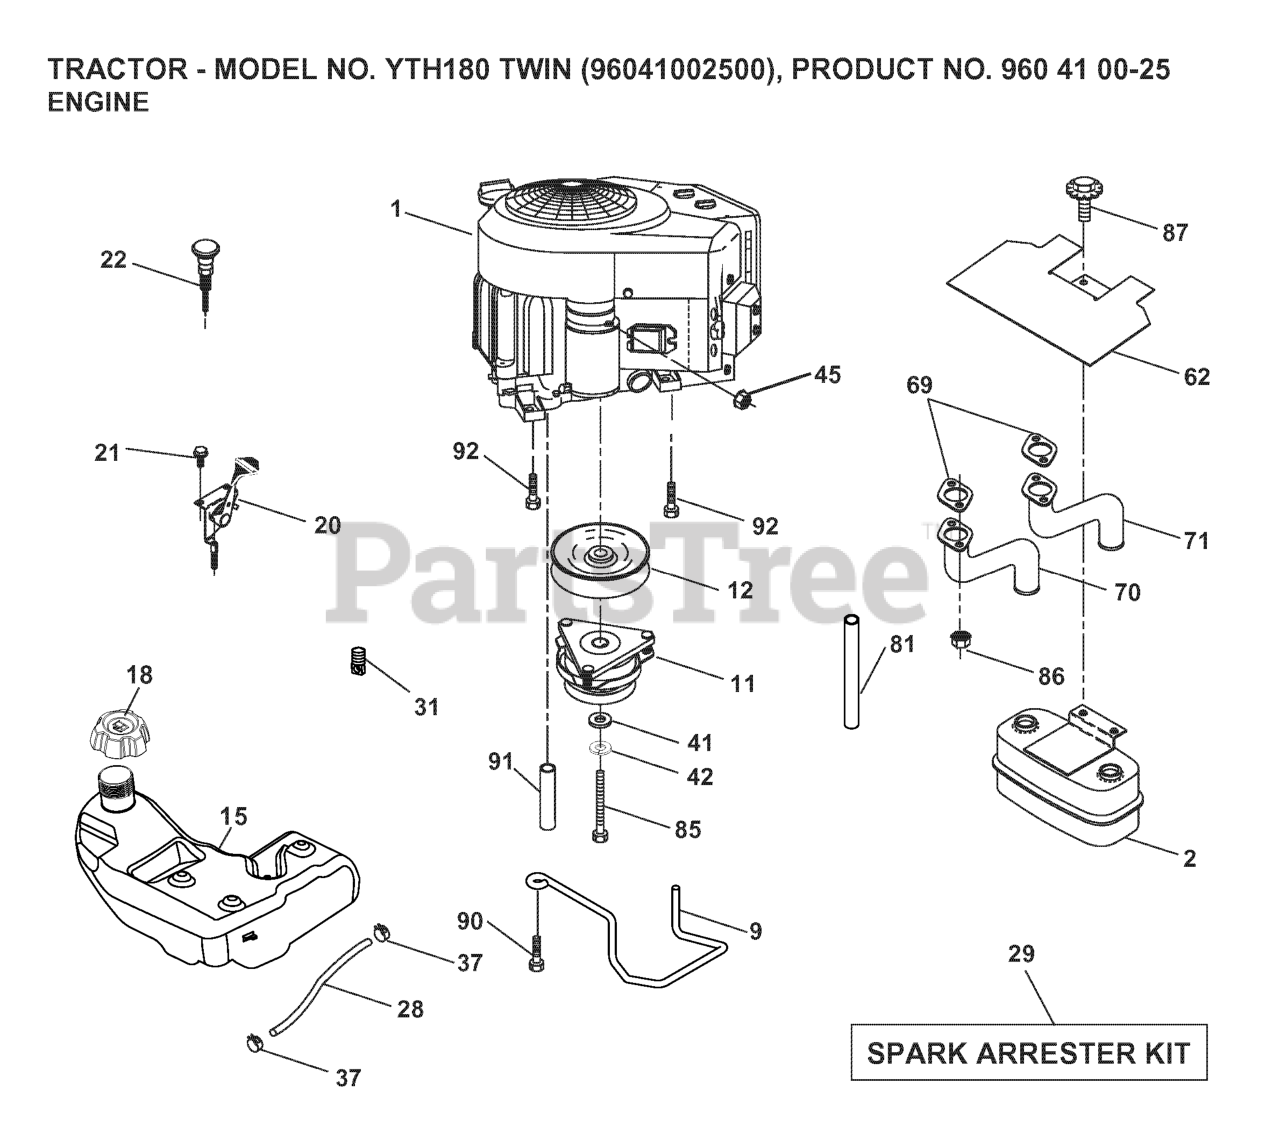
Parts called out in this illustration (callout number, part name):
2	MUFFLER.TWIN.CYL.LOW.TONE
9	KEEPER.BELT.ENGINE.4.2
11	RB.CLUTCH.OGURA.4.4.PD
12	PULLEY.ENGINE.TUFFTORQ
15	TANK.FUEL.4GAL
18	CAP.FUEL.TANK.3"GREY
20	THROTTLE CONTROL
21	SCREW
22	CONTROL, CHOKE
28	REPL BY 532 00 85-43
29	KIT.SPARK ARRESTOR 794945 B&S
37	HOSE CLAMP
42	LOCKWASHER
45	NUT
62	RP SHIELD HEAT MUFFLER
70	EXHAUST.TUBE.LH.KAWASAKI.
71	EXHAUST.TUBE.RH.KAWASAKI.
81	TUBE, DRAIN OIL ASM.
85	BOLT HEX 7/16-20X4-1/4"
86	NUT.HEX.FLANGE.TOPLOCK
87	BOLT.5/16-18UNCX1.W/SEMS.BLK
90	SCREW 3/8-16X1
91	BUSHING.1.375OD
92	SCREW 3/8-16X1
